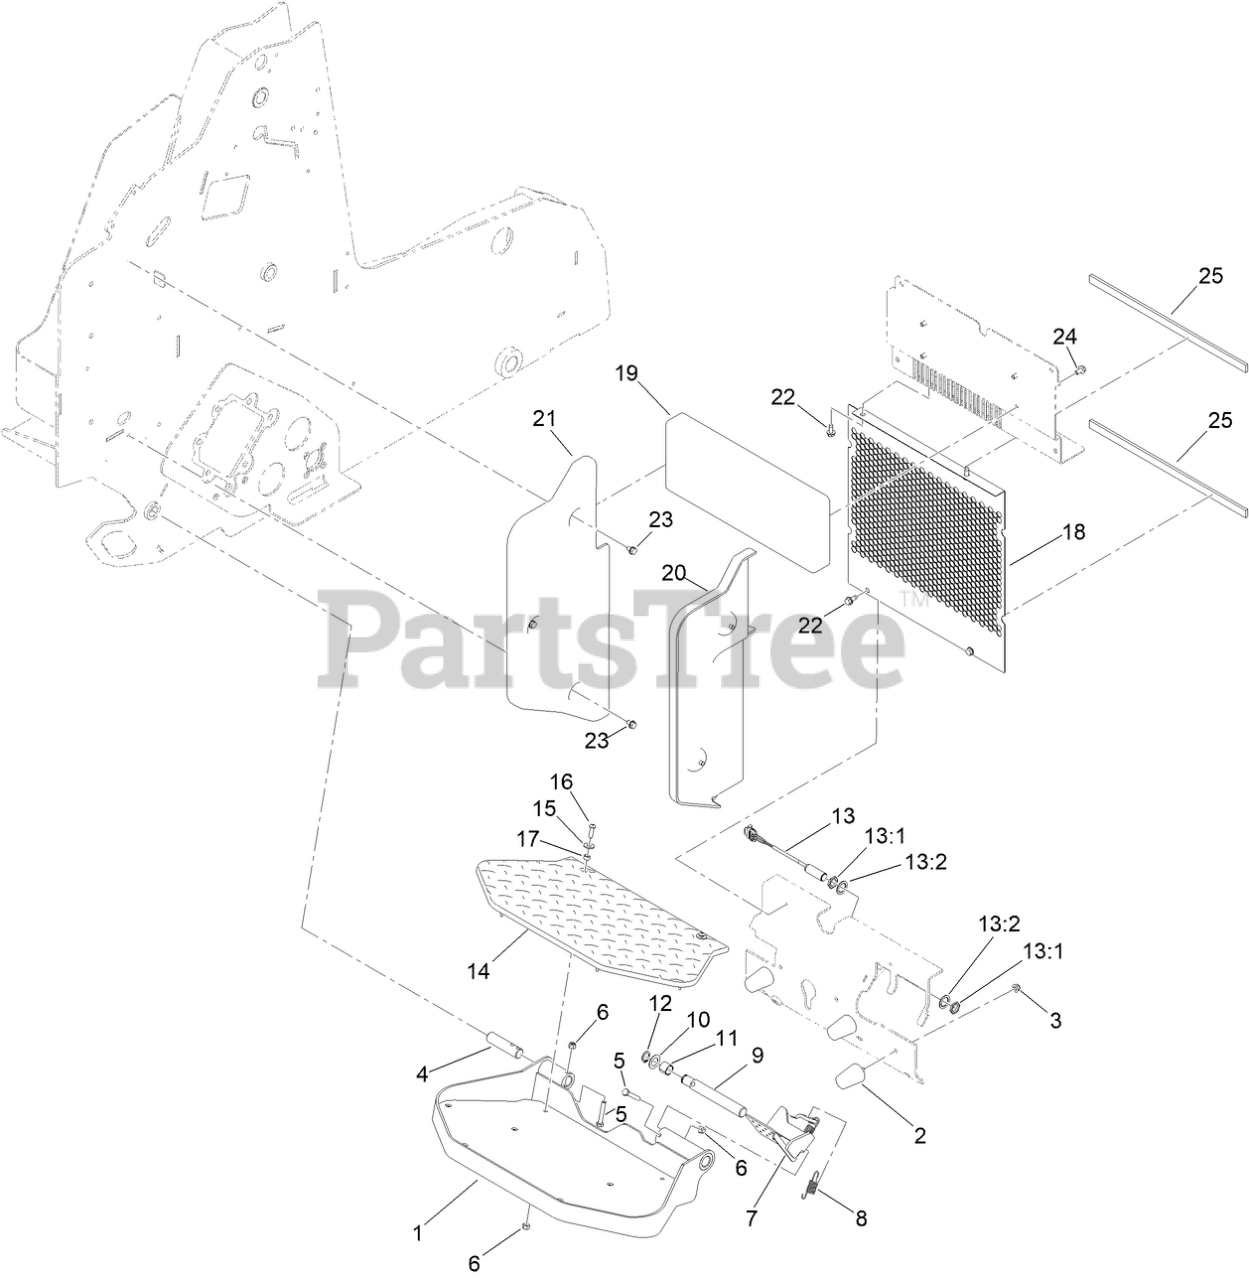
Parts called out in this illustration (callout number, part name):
1	PLATFORM ASM
2	BUMPER
3	NUT-HF, NI
4	PIN-PIVOT
5	SCREW-HH
6	NUT-LOCK, NI
7	AUX PEDAL ASM, [BLACK]
8	SPRING-EXTENSION
9	PIN-PLATFORM
10	WASHER-FLAT
11	BUSHING-STRAIGHT
12	RING-RETAINING
13	PROXIMITY SWITCH ASM
13:1	NUT-HEX
13:2	WASHER-LOCK, INTERNAL TOOTH
14	MAT-PLATFORM
15	WASHER-FLAT
16	SCREW-HSBH
17	SPACER-PIVOT, TILT
18	SCREEN-RADIATOR
19	CUSHION-PAD
20	COVER-RIGHT
21	COVER-LEFT
22	SCREW-HWHTF
23	SCREW-HWH
24	SCREW-HHF
25	PAD-RUBBER
